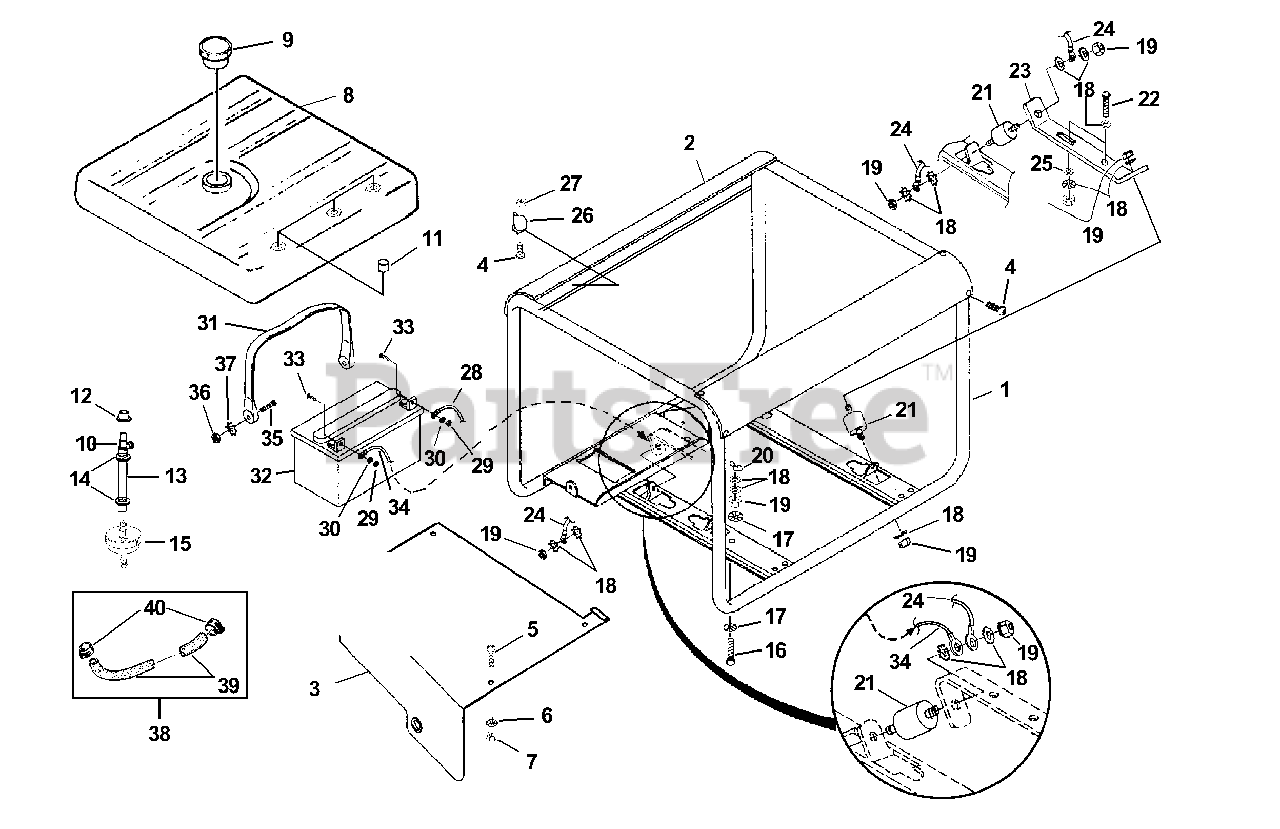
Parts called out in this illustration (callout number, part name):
1	Roll Cage-Recoil
2	Brace-Tank Support
3	Shield-Fuel Tank
4	Screw Serrated Hd.-Torx (10-24 X 1/2")
5	Screw-Pan Hd. (8-32 X 3/8")
6	Washer-Lock #8
7	Nut-Hex (8-32)
8	Fuel Tank (7 Gal.)
9	Cap-Fuel (2 1/4" Dia.)
10	Valve-Fuel
11	Pad-Fuel Tank
13	Hose-Fuel (8")
14	Clip-Hose
15	Fuel Filter
16	Screw-Hex Hd. (5/16-18 X 1 1/4")
17	Washer, Lock -Int - Ext. (3/8")
18	Washer-Lock (int.)
19	Nut-Hex (5/16-18)
20	Nut-Wing (5/16-18)
21	Isolator
22	Screw-Hex Hd. (5/16-18 X 3/4")
23	Support - Eng.
24	Ground Strap
25	Washer-Flat
26	Stop-Tank
27	Nut
28	Battery Cable (Red to Switch)
29	Nut-Hex (1/4-20)
30	Washer-Lock
31	Strap-Battery Hold Down
32	Battery (12 Volt)
33	Screw-Hex Hd (1/4-20 x 5/8")
34	Battery Cable (Black to Ground)
35	Screw-Shoulder (10-32 x 1/4")
36	Nut-Hex (10-32)
37	Washer-Lock
38	Fuel Pipe
39	Rubber Pipe
40	Hose Clamp
